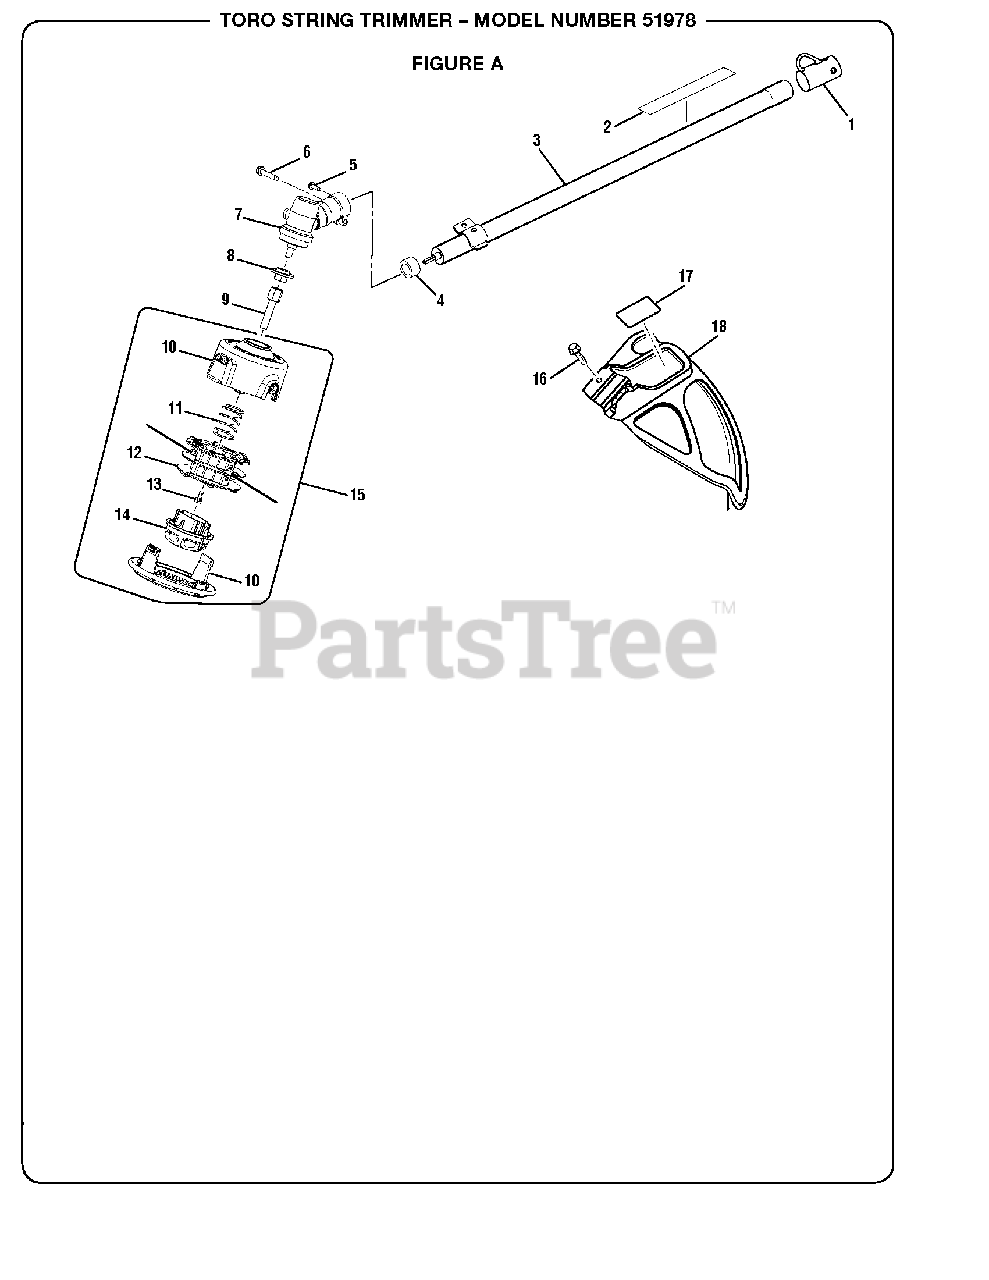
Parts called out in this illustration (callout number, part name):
1	Hanger Cap
2	Warning Label
3	Straight Shaft Assembly
5	Screw (10-24 x 5/8 in., Hex Washer Hd.)
6	Screw (1/4-20 x 1-1/4 in.)
7	Gear Head Assembly
8	Flanged Washer
9	Trimmer Head Shaft Adaptor
10	Stringhead Housing
11	Compression Spring
12	Spool
13	Bolt (5/16-18 x 1/2 in., L.H.)
14	Bump Knob
15	Trimmer Head Assembly
16	Screw (1/4-20 x 1-1/4 in., Hex Washer Hd.)
17	Grass Deflector Label
18	Grass Deflector Assembly
